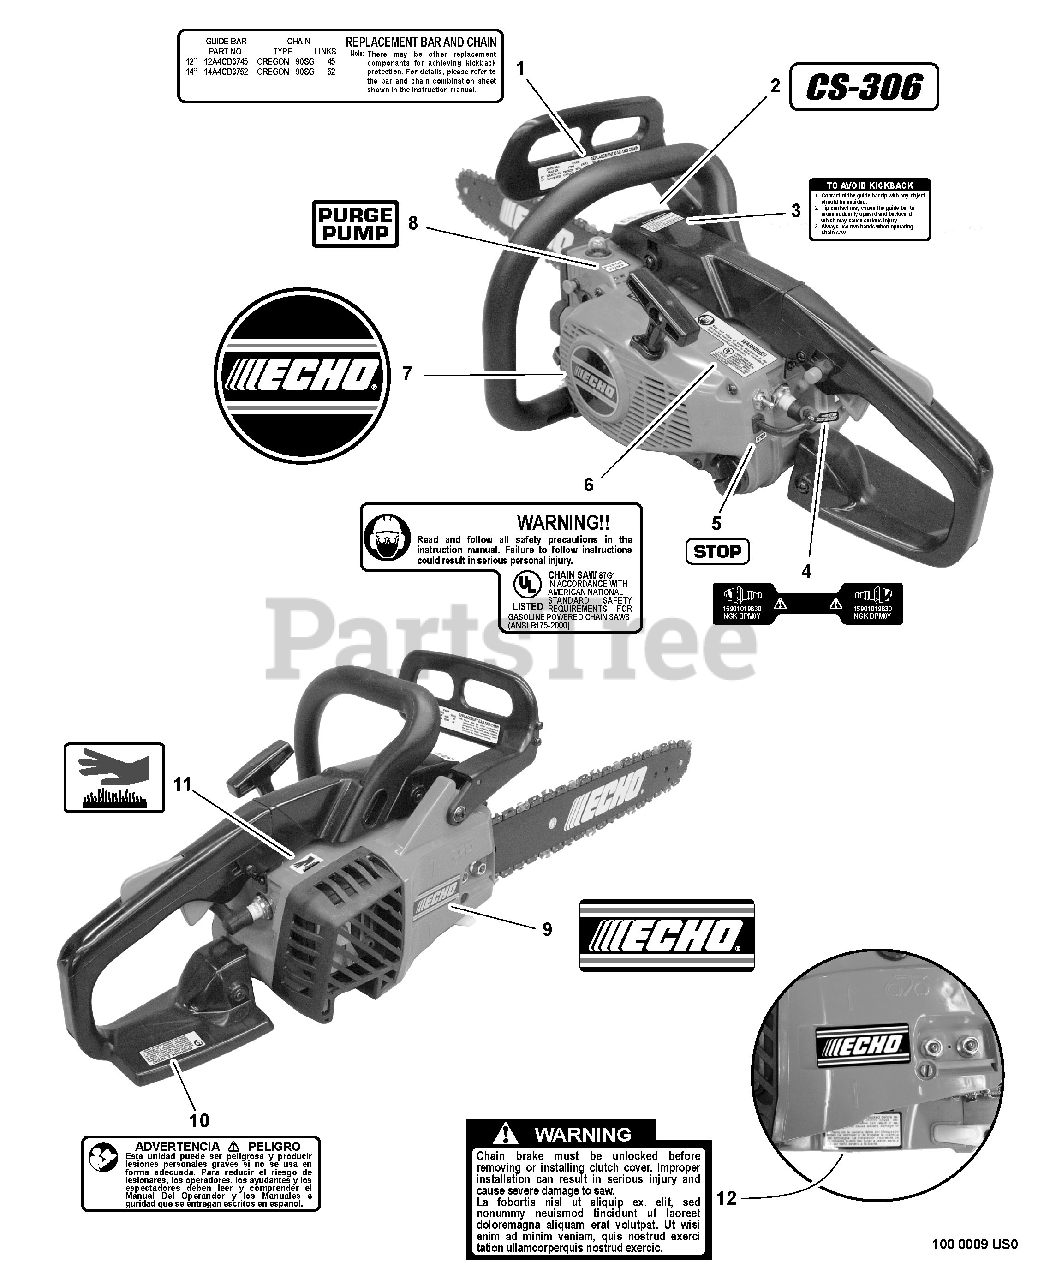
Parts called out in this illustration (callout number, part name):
1	LABEL - BAR & CHAIN
2	LABEL - MODEL CS-341
3	LABEL - WARNING -- KICKBACK
4	LABEL - SPARK PLUG -- BPMR-8Y
5	LABEL - STOP
6	LABEL - WARNING
7	LABEL - NOISE
8	LABEL - ECHO
9	LABEL - PURGE PUMP
10	LABEL - ECHO
11	LABEL - ATTENTION
12	LABEL - HOT SURFACE
13	LABEL - WARNING
